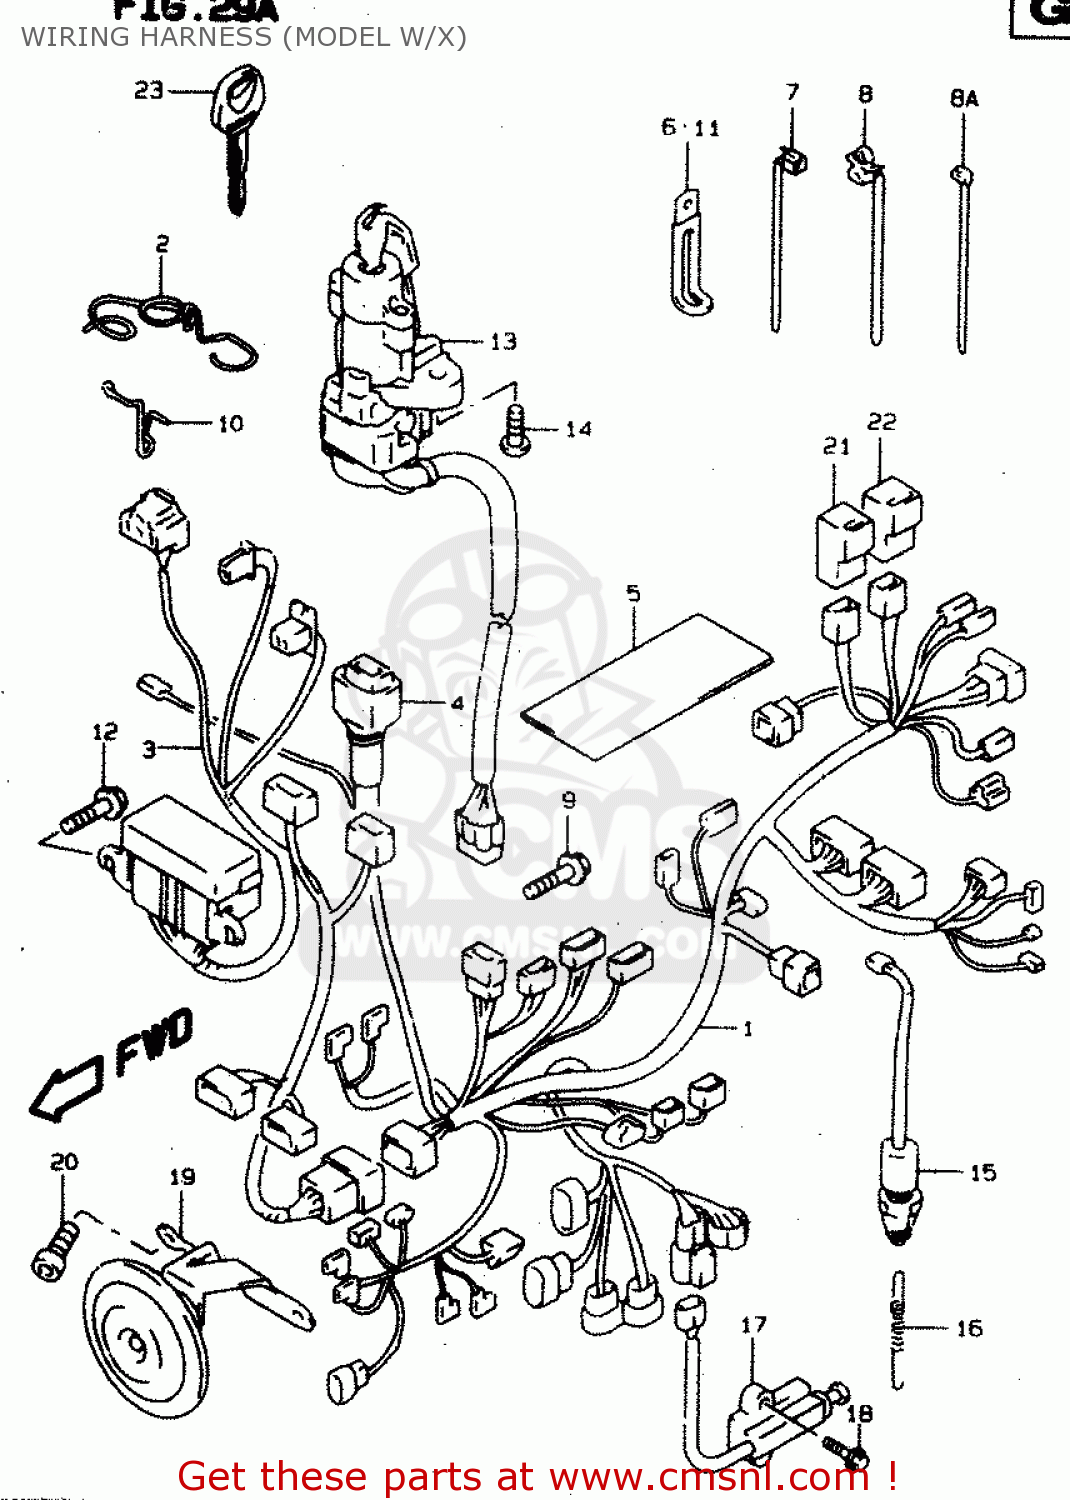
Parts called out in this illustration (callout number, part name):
1	HARNESS,WIRING NO.1
2	GUIDE,WIRING HARNESS
3	HARNESS,WIRING NO.2
4	COVER,SPEEDOMETER COUPLER
5	PROTECTOR,WIRING HARNESS
6	CLAMP(L:65)
7	CLAMP(L:125)
8	CLAMP
8A	CLAMP(L:145)
9	BOLT
10	STOPPER,FUSE BOX
11	CLAMP(L:80)
12	SCREW 6X12
13	LOCK ASSY,STEERING
14	BOLT(8X20)
15	SWITCH ASSY,STOP LAMP
16	SPRING
17	SWITCH ASSY,SIDE STAND WARNING
18	BOLT
19	HORN ASSY
20	BOLT
21	RELAY ASSY
22	RELAY ASSY
23	KEY,BLANK
